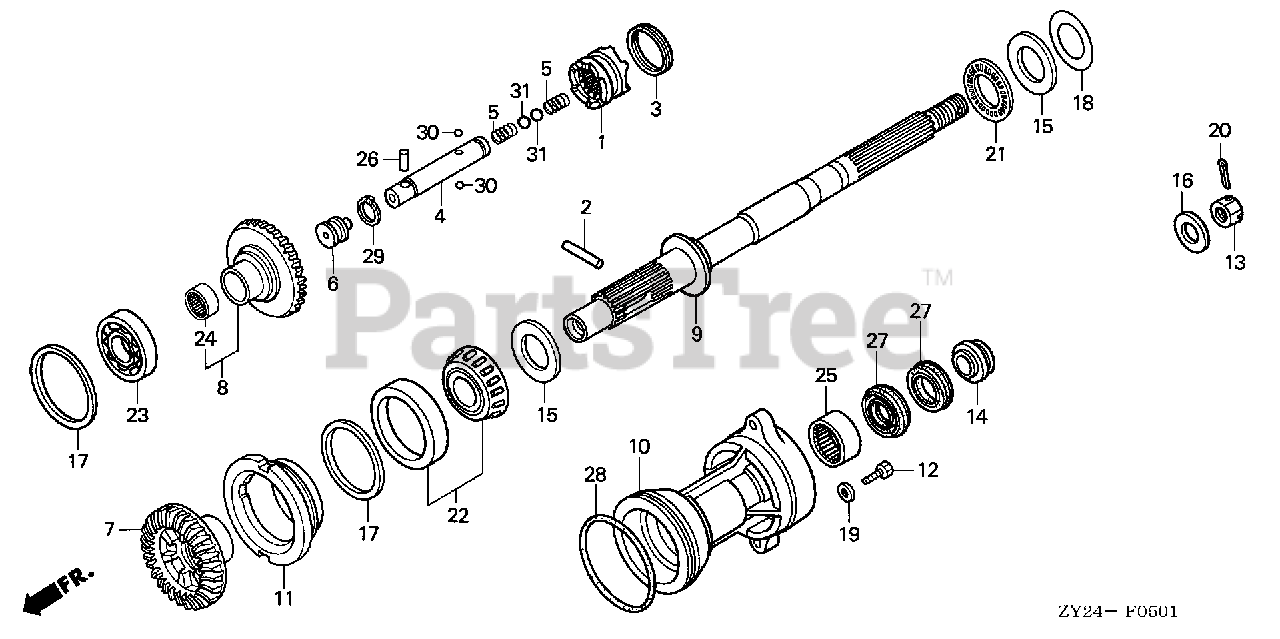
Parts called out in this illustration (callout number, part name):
1	SHIFTER, CLUTCH
2	PIN, SHIFTER (8X50)
3	RING, CROSS PIN
4	SLIDER, SHIFT
5	SPRING, SHIFT
6	PLATE, SHIFT
7	GEAR, BEVEL (FORWARD 28T) (COUNTER ROTATION)
8	GEAR, BEVEL (RVS. 28T) (COUNTER ROTATION)
9	SHAFT, PROPELLER
10	HOLDER, PROPELLER SHAFT *NH282MU* (OYSTER SILVER METALLIC-U)
11	HOLDER, BEARING (COUNTER ROTATION)
12	BOLT, HEX. (12X45)
13	NUT, CASTLE (18MM)
14	WASHER, PROPELLER THRUST
15	WASHER, THRUST BEARING
16	WASHER, PROPELLER
17	SHIM A, BEVEL (0.10)
17	SHIM B, BEVEL (0.15)
17	SHIM C, BEVEL (0.30)
17	SHIM D, BEVEL (0.50)
18	SHIM A, THRUST (0.10)
18	SHIM B, THRUST (0.15)
18	SHIM C, THRUST (0.30)
18	SHIM D, THRUST (0.50)
19	WASHER, PLAIN (12MM)
20	PIN, SPLIT (4.0)
21	BEARING, THRUST (F)
22	BEARING, TAPER (50X90X21.5)
23	BEARING, ANGULAR (50X90X30.2)
24	BEARING, NEEDLE (28X39X30)
25	BEARING, NEEDLE (32X42X30)
26	ROLLER (4X13.8)
27	SEAL, WATER (30X45X7)
28	O-RING (105X3.1)
29	CIRCLIP (OUTER) (15MM)
30	BALL, STEEL (#7) (7/32)
31	BALL, STEEL (#12) (3/8)
